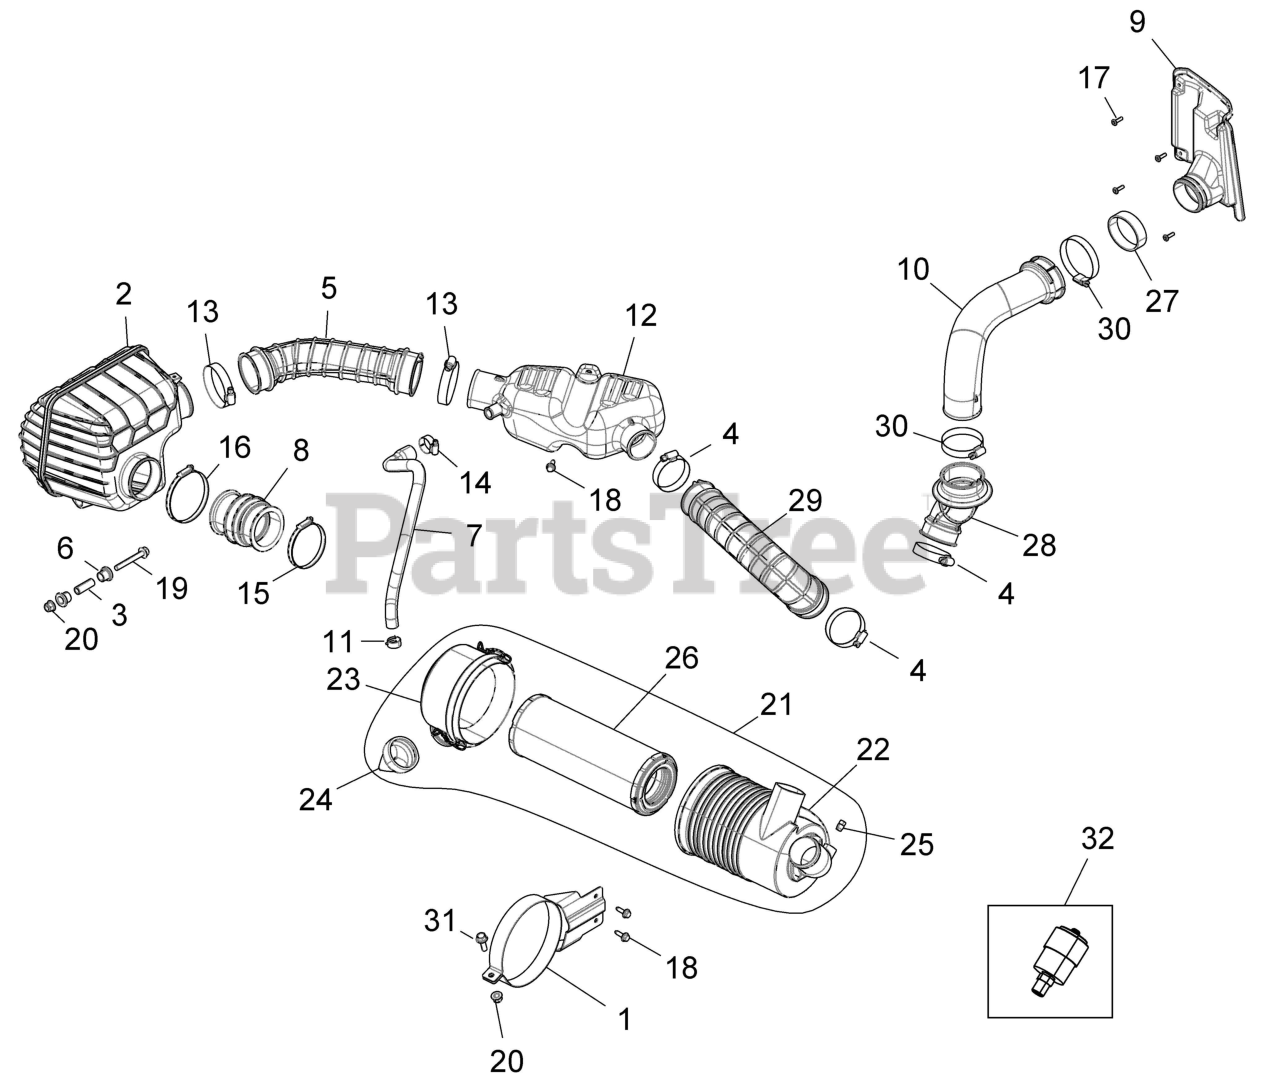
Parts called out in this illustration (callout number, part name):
1	WELD-AIRBOX,MOUNT
2	WELD-INTAKE,PLENUM
3	SHAFT-COMPRESSION LMTR,34.4MM
4	CLAMP, HOSE, S.S.(10)
5	HOSE, ENGINE INTAKE
6	BUSHING-MOUNT
7	HOSE-VENT,ENG
8	BOOT-THROTTLE BODY
9	INTAKE-FENDER,REAR,BLK
10	DUCT-INTAKE,AIR
11	CLAMP, HOSE, SPRING
12	DUCT-INTAKE,ENG
13	CLAMP-HOSE, 2.75"-SS
14	CLAMP,HOSE
15	CLAMP,BAND,NARROW (10)
16	CLAMP-BAND,NARROW 70-90MM
17	SCR-10X5/8-HI/LO,PN-T25,TRX-M
18	SCR-M6X1.0X20,HXHD,FLG,TDFM,BL
19	SCR-HXFL-M8X1.25X60 8.8 ZOD
20	NUT-M8X1.25,FLG,NYLOC-OLIVE D
21	ASM., AIR INTAKE
22	ASM., AIRBOX, MAIN
23	ASM-LID,AIRBOX
24	VALVE-AIRBOX
25	PLUG-AIRBOX
27	HOSE-INTAKE,BOOT
28	HOSE-INTAKE,AIR BOX,SPLY
29	HOSE-AIR BOX,SPLY
30	CLAMP, HOSE
31	BOLT-M8X1.25X25,HXFLG-OLIVE D
32	KIT, FILTER, INDICATOR
